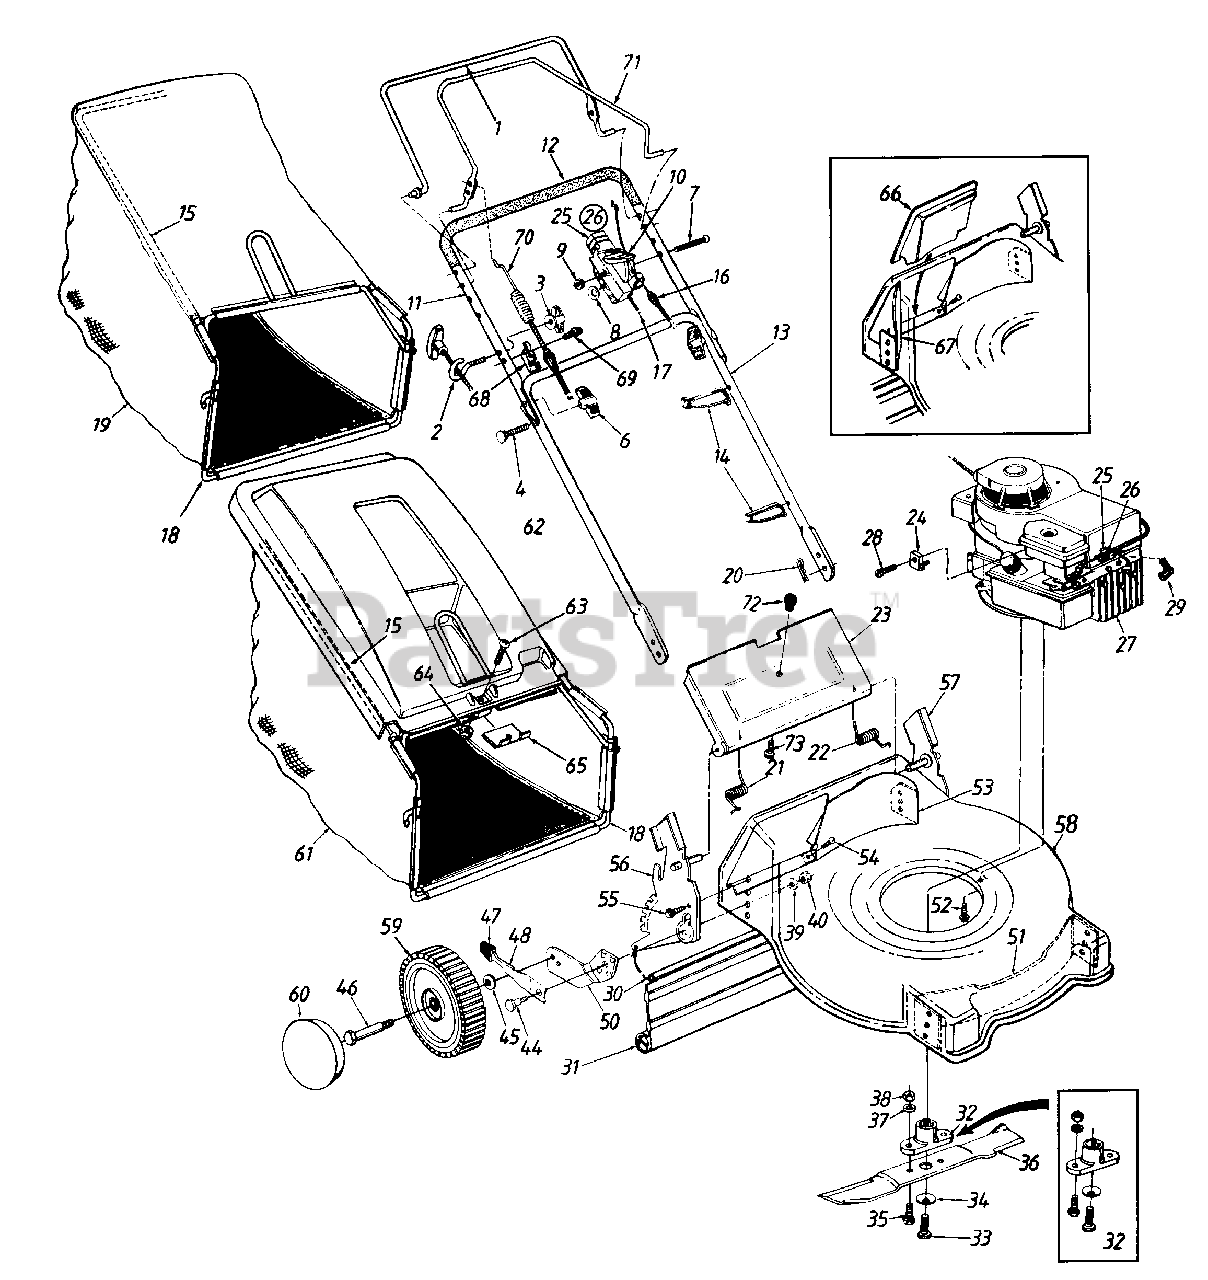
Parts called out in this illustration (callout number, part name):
2	Rope Guide
3	Handle Knob 1/4-20 Thd.
4	Curved Hd. Bolt 5/16-18 x 2" Lg.
6	Hand Knob
7	Oval C-Sunk Mach. Scr.
8	Spr. Wash. .66" I.D.
9	Hex L-Nut 1/4-20 Thd.
10	Throttle Lever
14	Cable Tie
16	Control Cable-39"
17	Throttle Control Wire-42"
20	Int. Cotter Pin 5/16" Dia.
21	Door Spring-R.H.
22	Door Spring-L.H.
25	Throttle Body
26	Throttle Box Comp.
27	Engine
28	Hex Wash. Hd. Scr. #10-32 x .62" Lg. (B&S)
29	Spark Plug Boot
30	Wire Rod
31	Rear Flap
32	Blade Adapter Kit
33	Hex Bolt 3/8-24 x 1.5" Lg.
34	Bell-Wash. 39" I.D.
35	Hex Bolt 3/8-24 x 1" Lg.
36	21" Blade
37	L-Wash. 3/8" I.D.
38	Hex Nut 3/8-24 Thd.
39	Bell-Wash. .39" I.D. x 1.38"
40	Hex Nut 3/8-16 Thd.
44	Shld. Bolt .5" Dia. x .357"
45	Bell-Wash. .38" I.D. x .88" O.D.
46	Axle Bolt
47	Spring Lever Knob
48	Spring Lever
50	Pivot Bar
54	Torx Mach. AB-Tap Scr. 1/4 x .62" Lg.
55	Hex L-Wash. Hd. AB-Tap Scr. 1/4 x .62" Lg.
56	Handle Brkt. Ass'y.-R.H.
57	Handle Brkt. Ass'y.-L.H.
60	Hub Cap 3-1/2" Dia.
61	Grass Bag
62	Hard Top Cover
63	Pan Hd. Mach. Scr. 1/4-20 x .5" Lg.
64	Hex Nylon L-Nut 1/4-20 Thd.
68	Cable Mtg. Brkt.
69	Hex Wash. AB-Tap Scr. 5/16" x .75" Lg.
70	S.P. Cable 44.75" Lg.
73	Truss Mach. Scr. #10-24 x .38" Lg.
